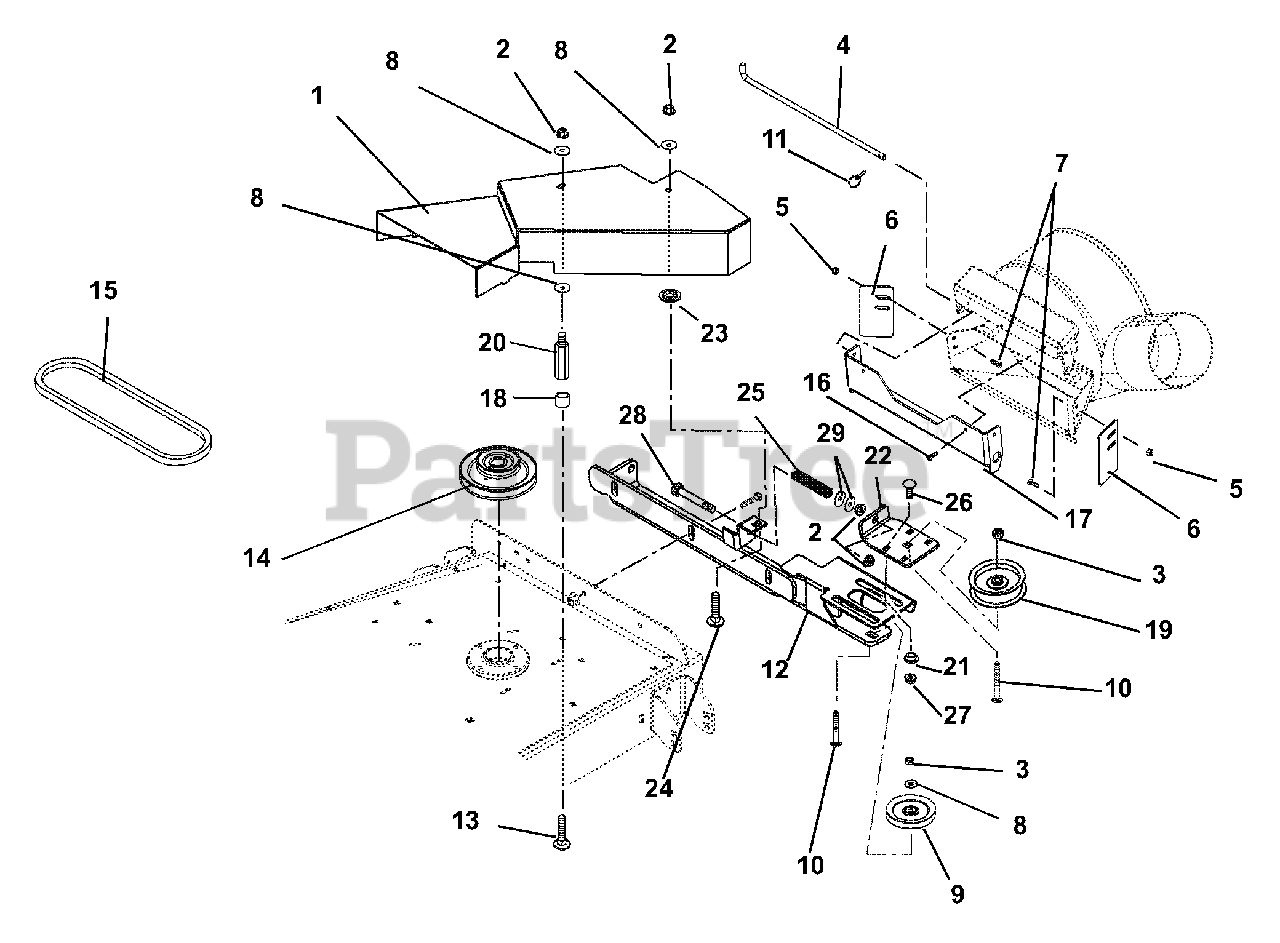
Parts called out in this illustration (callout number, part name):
1	Weldment, Belt Guard
2	Nut-Locking-Top-Flange .31-18
3	Nut, Top Lock Flange .38-16
4	Rod-Pivot
5	Nut-Locking-Top-Flange .25-20
6	Bar, Extension
7	Bolt-Round Head Square Neck .25-20 x .75
8	Washer-Flat-Steel .438 x 1.00 x .083
9	Idler-V 4.00 x .38
10	Bolt-Round Head Square Neck .38-16 x 1.75 Grade 5
11	Pin-Klik 1.00 x .188 x 1.25
11	(Gravely Part Number)
12	Weldment, Pivot Mounting Bracket
13	Bolt-Round Head Square Neck .31-18 x 2.25 Grade 5
14	Pulley, Double V 3.50/6.25 Dia.
15	V-Belt, 48-78 78 Outer Circle
16	Screw-Tapping .25-20 x .50 Hex Washer Head Thread Rolling
17	Weldment, Blower Mount
18	Spacer .380 x .625 x 1.50
19	Idler, Flanged 3.50
20	Stand Off, 2.75 x 5/16-18
21	Bushing-Flange .265 x .437 x .250 x .750]
22	Bracket, Adjustable Idler
23	Nut-Push .312
24	Bolt-Round Head Square Neck .31-18 x .75 Grade 5
25	Spring-Compression .080 x .52 x 2.90
26	Bolt-Round Head Square Neck .25-20 x .75 Grade 5
27	Nut-Locking-Top-Flange .25-20
28	Bolt-Hex .31-18 x 4.00 Grade 5
29	Washer-Flat-Steel .406 x 1.00 x .188
